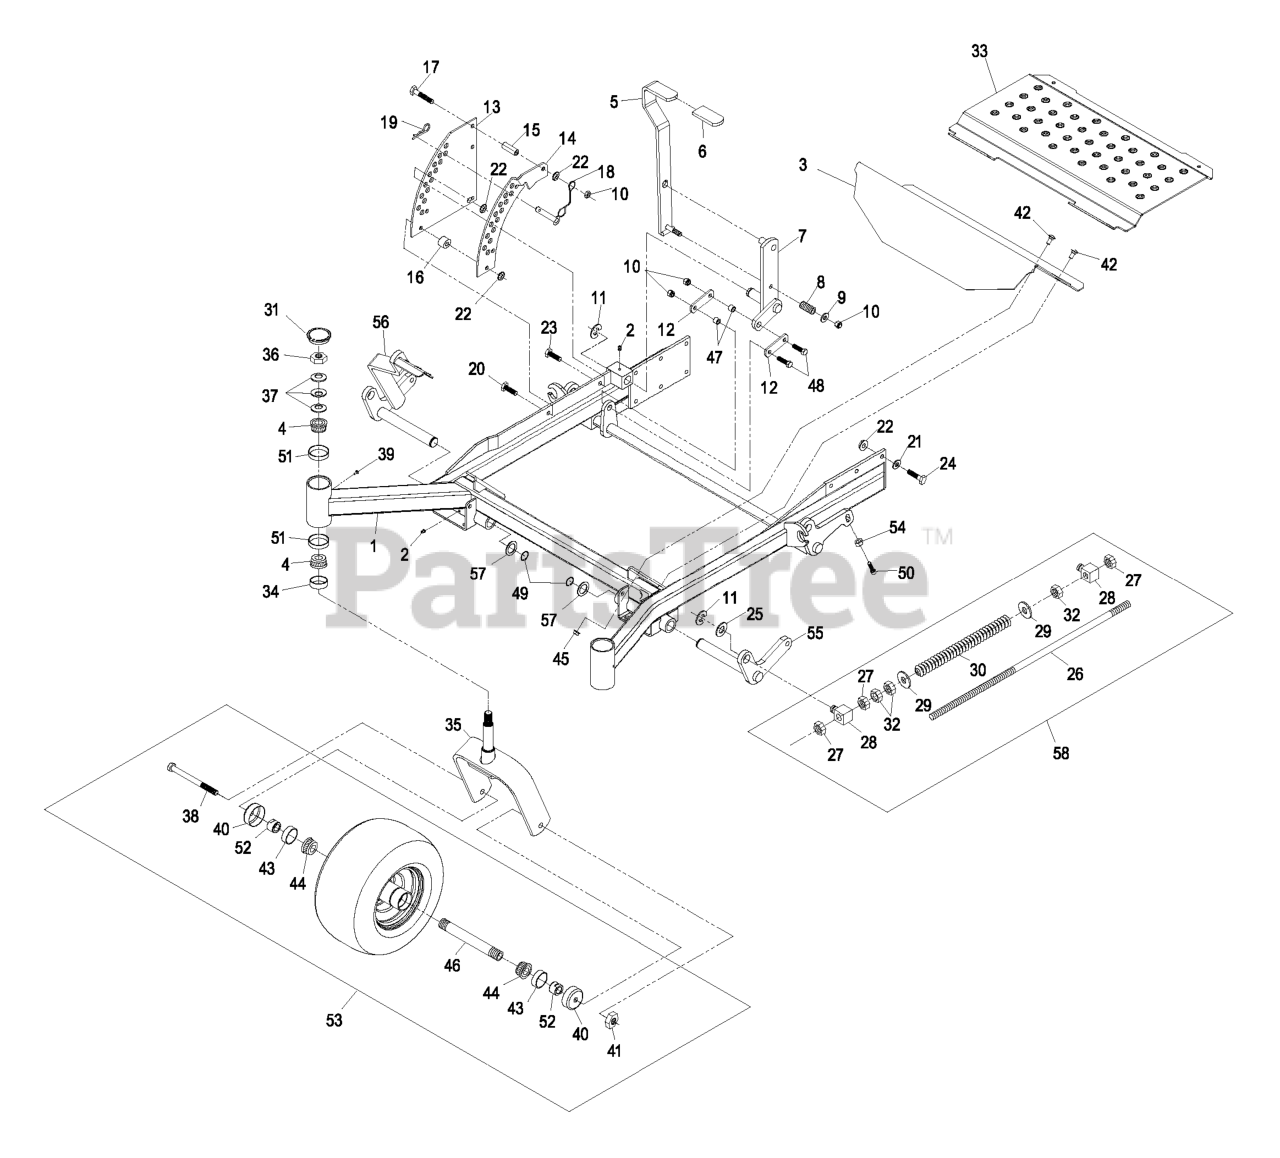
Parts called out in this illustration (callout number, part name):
1	ASM, FRONT FRAME 60"
2	FITTING-GREASE
3	ASM, FLOORPAN FRONT W/DEC
4	Cone-Bearing Tapered Roller
5	LIFT LEVER/GRIP ASM
6	GRIP-LEVER, LIFT
8	SPRING-COMPRESSION
9	WASHER-FLAT
10	NUT-LOCK, NI
11	RING-RETAINING, EXT
12	ARM-LIFT, DECK
13	PLATE-LIFT, DECK
14	PLATE-LIFT, DECK
15	BUSHING-LEVER, LIFT
16	Stop, Deck Height
17	SCREW-HH
18	PIN-HITCH (W/LANYARD)
19	PIN-COTTER
20	SCREW-HH
21	WASHER-BELLEVILLE
22	NUT-HHF, WHIZ
23	SCREW-HH
24	SCREW-HH
25	WASHER-FLAT
26	ROD-LIFT, DECK
27	NUT-HEX
28	SWIVEL-DECK MOUNT, REAR
29	WASHER-FLAT
30	SPRING,DECK SUPPORT
31	CAP-GREASE
32	NUT-JAM
33	ASM, FLOORPAN LIFTOUT W/D
34	SEAL-GREASE
36	NUT-LOCK, NI
37	WASHER-BELLVILLE
38	SCREW-HH
40	GUARD-SEAL
41	NUT-LOCK, NI
42	BOLT-CARR
43	SEAL-CASTER
44	BEARING-CONE, TAPERED ROLLER
47	BUSHING
48	SCREW-HH
49	RING-RETAINING
50	SCREW-HSH
51	CUP-BEARING
52	SPACER-NUT
54	NUT-JAM
55	WLD,FRONT LIFT SHAFT-LH
56	WLD,FRONT LIFT W/LEVER
57	WASHER-SPACER
58	ASM,FRONT FRAME SPRING
